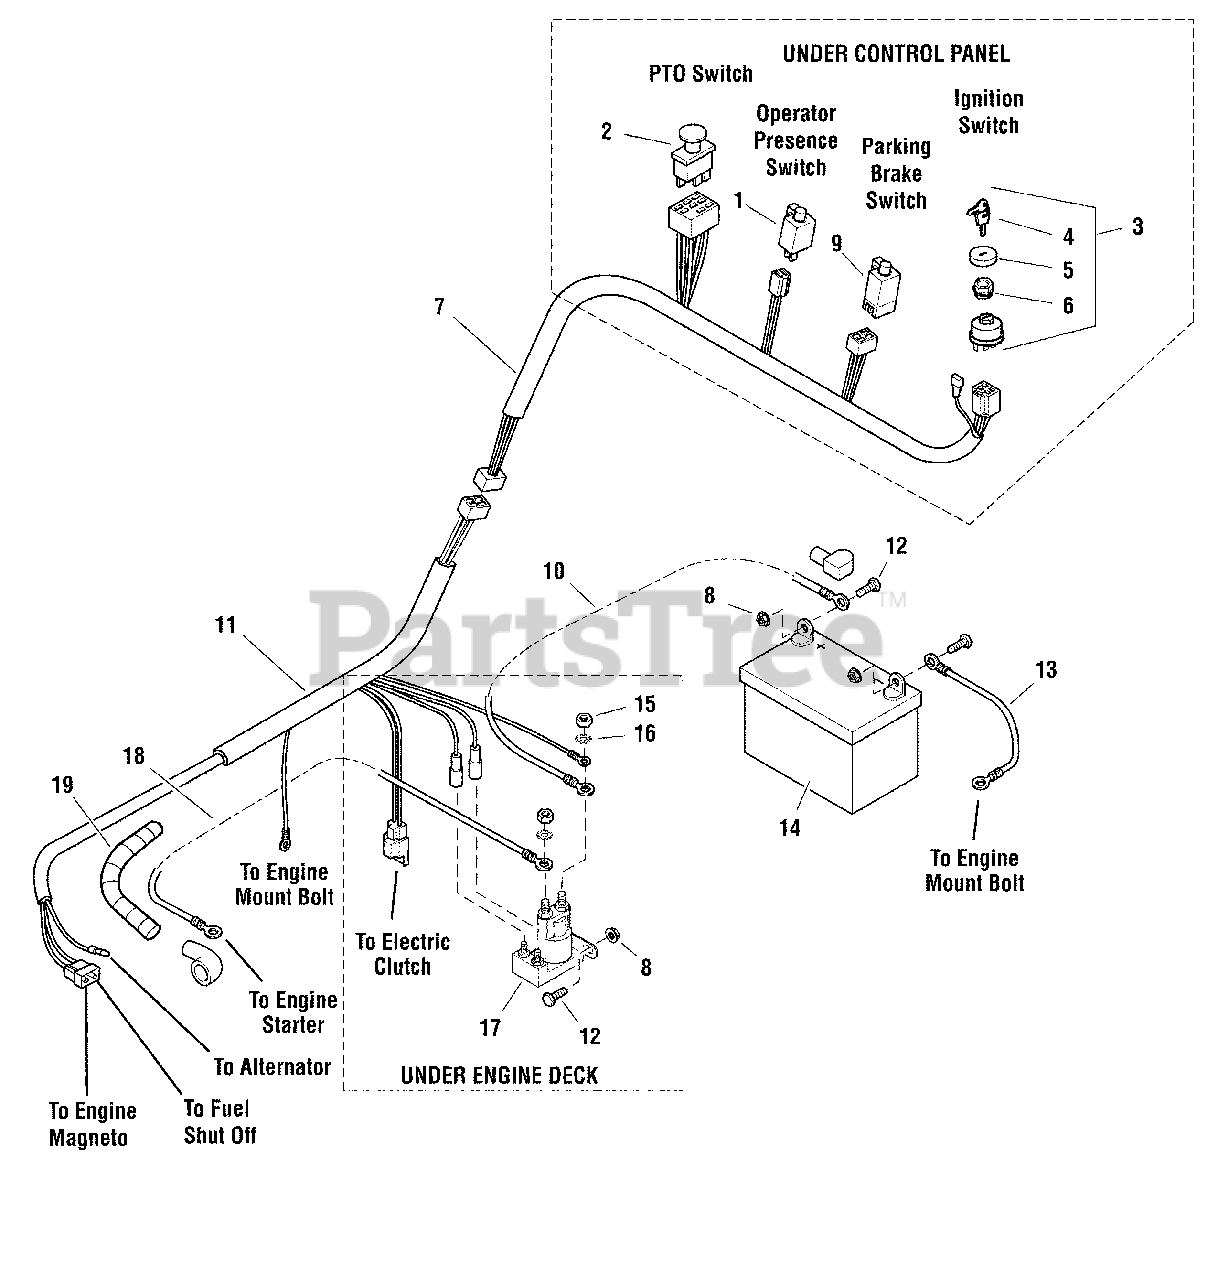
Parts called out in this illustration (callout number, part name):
1	SWITCH, PLUNGER NC
2	SWITCH, BLADE ENGAGEMENT
3	SWITCH, IGNITION, 6 POST
4	KEY, IGNITION, MOLDED SET
5	COVER, PLASTIC SNAP ON
6	NUT, PLASTIC
7	WIRE HARNESS, HANDLE BAR
8	NUT, 1/4-20 HEX SERRATED FLANGE
9	SWITCH, PLUNGER, N.O./N.C.
10	BATTERY CABLE, POSITIVE, 22"
11	WIRE HARNESS, ENGINE DECK, BRIGGS, PACER
12	BOLT, 1/4-20 X 3/4
13	BATTERY CABLE, NEGATIVE, 40" LONG
14	BATTERY, WET ( BCIU1, 340 CCA)
15	NUT, HEX JAM 5/16-24
16	WASHER, LIGHT LOCK, 5/16
17	SOLENOID-4 POLE 12 VOLT DC (TROMBETTA)
18	BATTERY CABLE, POSITIVE, 35" LONG
19	WIRE LOOM, 3/8 ID X 30 IN
